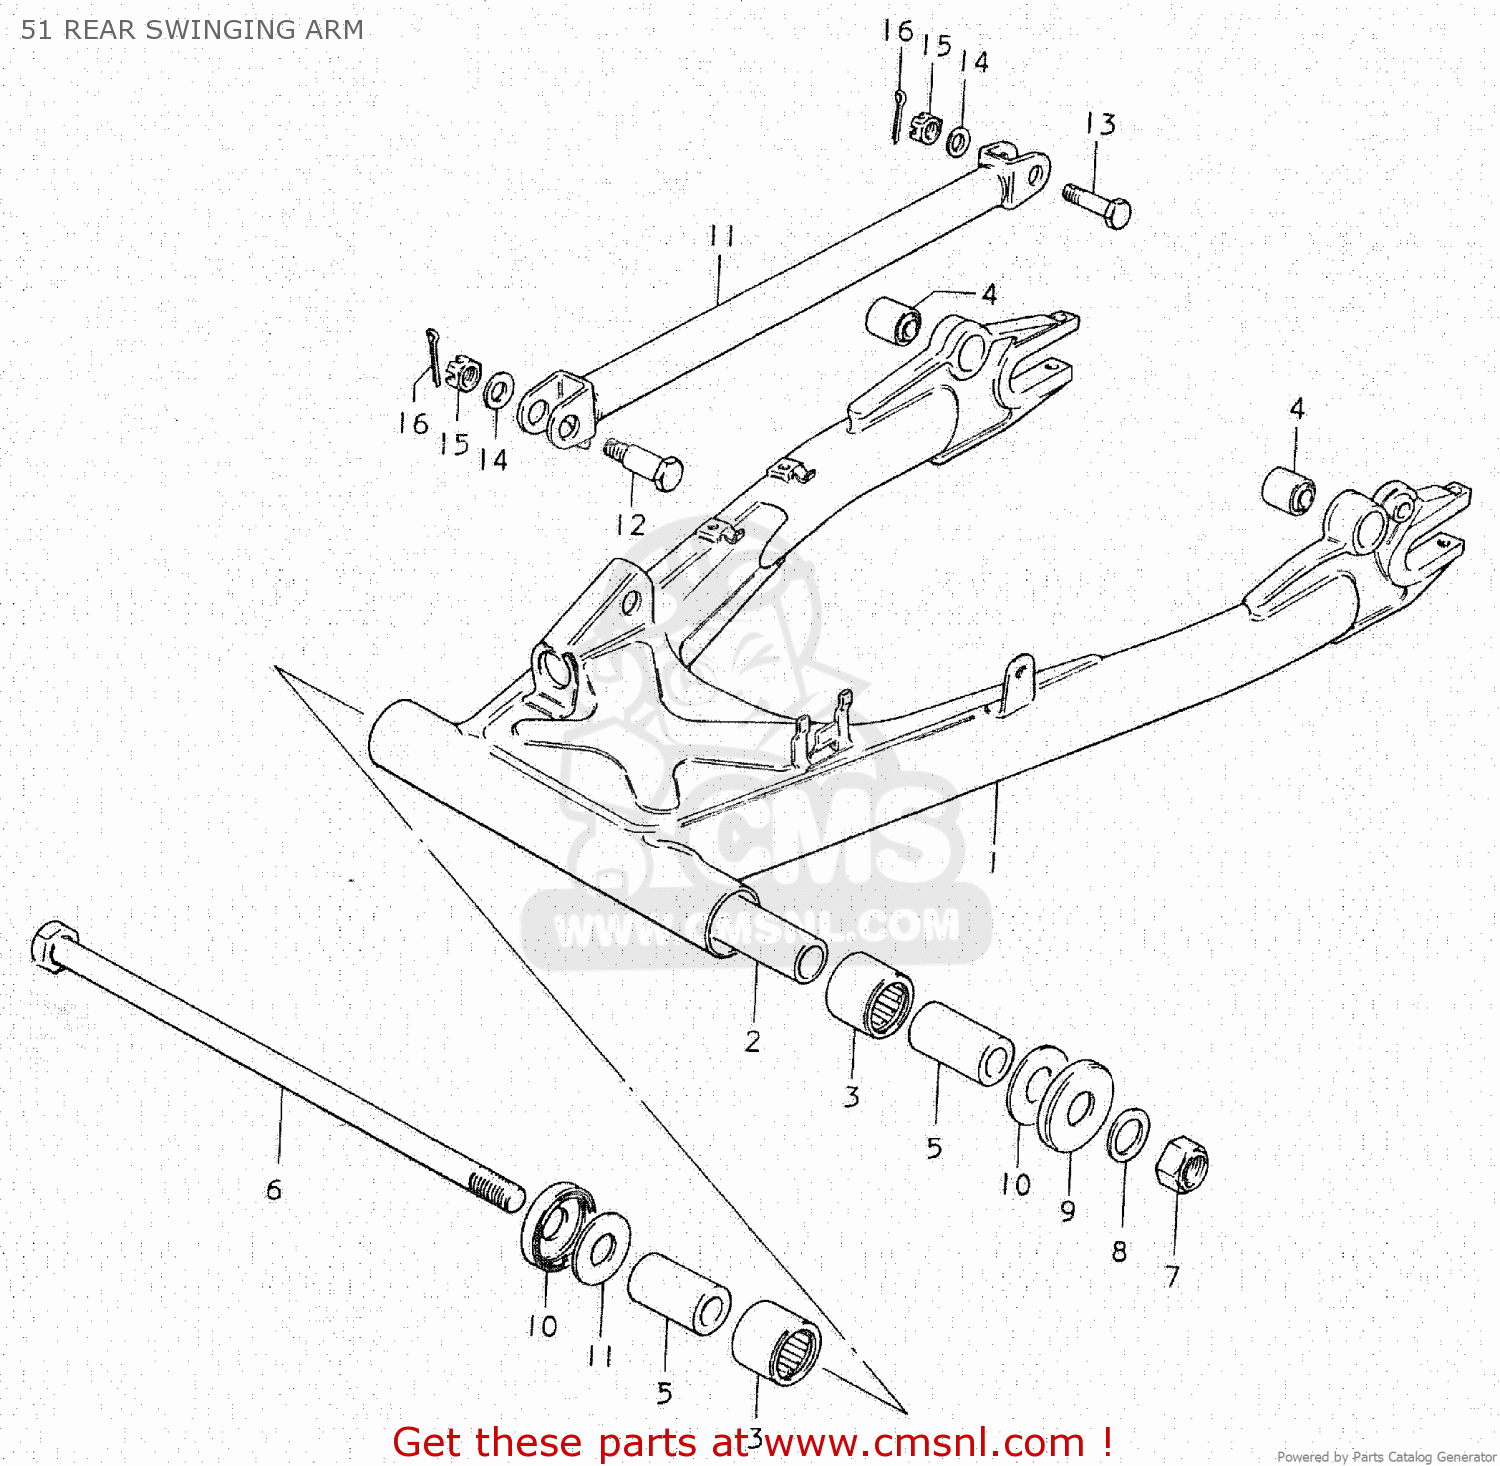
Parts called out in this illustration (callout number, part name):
1	SWING ARM ASSEMBLY,REAR
2	SPACER,SWING ARM,CENTER
3	BEARING(22X29X30)
4	BUSH
5	SPACER,RR SWGARM PIVOT
6	SHAFT,REAR SWING ARM
7	NUT 14MM
8	WASHER
9	COVER,REAR SWING ARM DUST
10	WASHER(14.2X34X1)
11	LINK,REAR TORQUE
12	BOLT
13	BOLT(10X39)
14	WASHER
15	NUT
16	PIN 20X20
